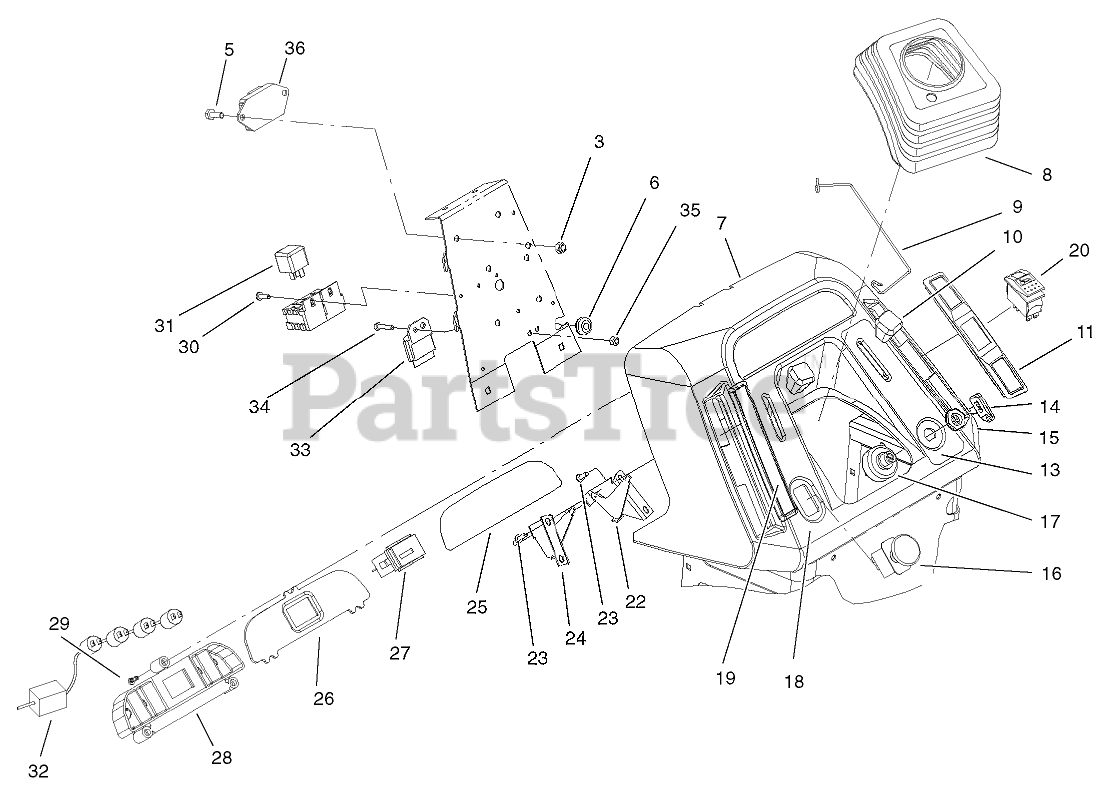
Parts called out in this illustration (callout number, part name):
3	NUT-LOCK, NI
5	SCREW-HH
8	BOOT-STEERING
9	CLIP-BOOT
11	Cover-RH Slot (only on: 72087)
11	Cover-RH Slot (only on: 72107)
13	Decal-Throttle, Ignition (only on: 72087)
13	Decal-Dash (only on: 72107)
14	KEY-IGNITION
16	SWITCH-PTO
17	SWITCH-IGNITION
18	Decal-Dash PTO/Choke (only on: 72107)
18	Decal-PTO/Choke (only on: 72087)
19	COVER-SLOT, LH
20	SWITCH-CRUISE
22	CONTROL-THROTTLE (TWIN)
24	CONTROL-CHOKE (TWIN)
25	DECAL-LENS, DASH
26	LENS-DASH
27	HOURMETER
28	HOUSING-LIGHT, INDICATOR
29	SCREW
30	SCREW-PPHTF
31	RELAY
32	HARNESS-4 LAMP
33	MODULE-LOW VOLTAGE
35	NUT-LOCK, NI
36	MODULE-CLUTCH
